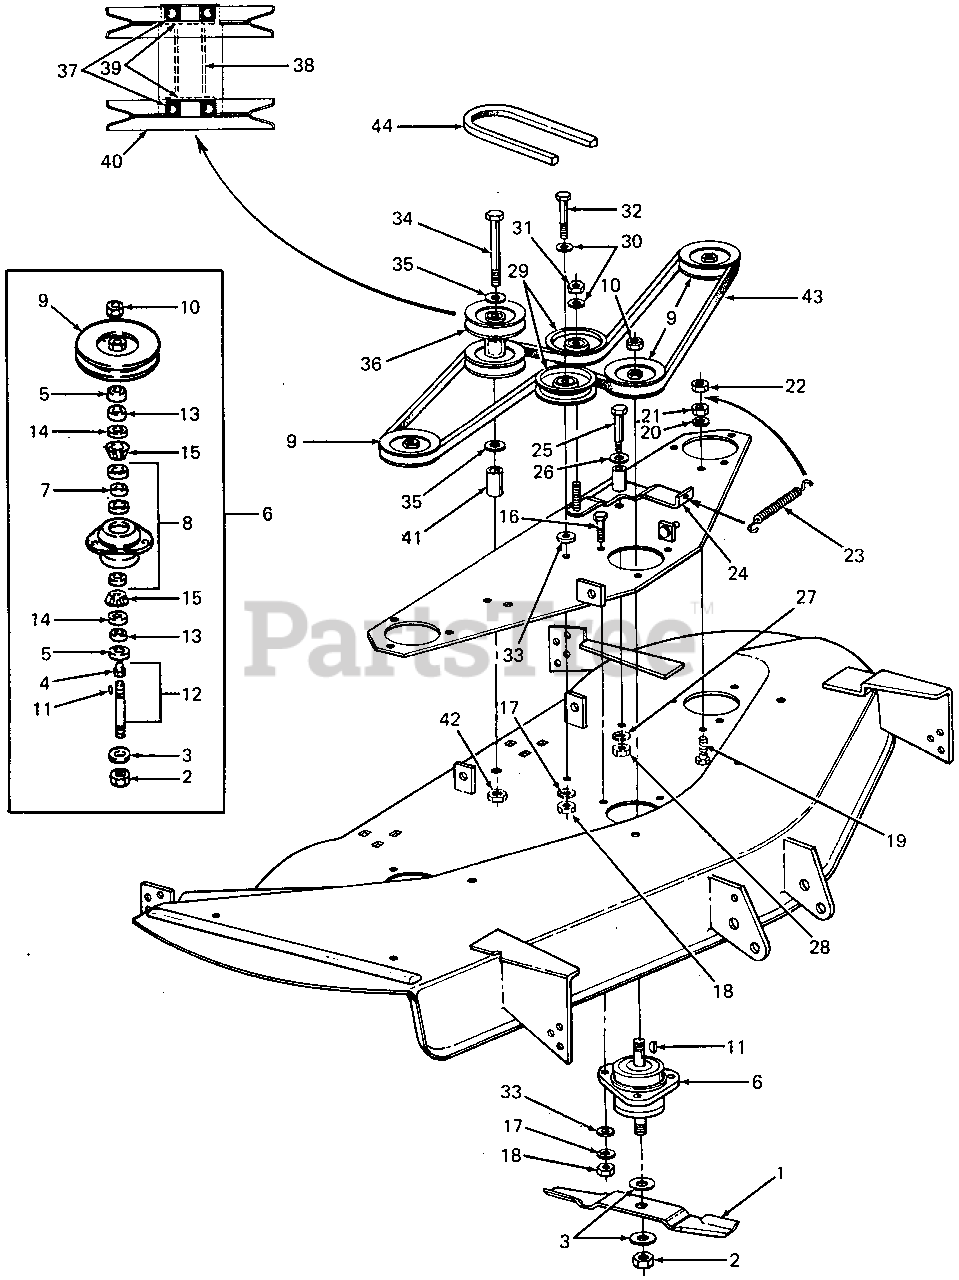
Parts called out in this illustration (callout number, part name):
2	Nut, Hex, 3/4-16 GR8
3	Washer, Flat, .781 X 2.0 X .105 Thk HDN
4	Fitting, Lube, 3/16
5	Cup, Spindle HDN
6	Spindle Service Kit
7	Spacer, Bearing
8	Housing, Spindle w/Cups
9	4L V-Pulley, 4.62 OD X .75 ID
10	Nut, Hex Jam, 3/4-16
11	Key, #91 Woodruff, 1/4 X 3/4 HDN
12	Kit, Shaft w/Seal
13	Spacer, .755 X 1.25 X .44 Lg
14	Seal, Oil, 1.25 X 1.874 X .25
15	Cone, Bearing
16	Screw, Hex Cap, 3/8-16 X 1.0 Lg GR5
17	Washer, Lock, 3/8
18	Nut, Hex, 3/8-16
19	Screw, Hex Cap, 5/16-18 X 1.5 Lg GR5
20	Washer, Lock, 5/16
21	Nut, Hex, 5/16-18
22	Nut, Hex Center Lock, 5/16-18 GR5
23	Spring, Extension, .81 OD X 4.75 Lg
24	Arm, Idler
25	Bolt, Shoulder, .68 Dia X 1.56 Lg X 7/16-14 Trd
26	Washer, Flat, .793 X 1.24 X .060 Thk
27	Washer, Lock, 7/16
28	Nut, Hex, 7/16-14 GR5
29	Pulley, Flat Idler, 3.88 OD X .38 ID
30	Washer, Flat, .406 X .75 X .063 Thk
31	Nut, Hex Center Lock, 3/8-16 GR5
32	Screw, Hex Cap, 3/8-16 X 2.0 Lg GR5
33	Washer, Flat, .385 X 1.0 X .127 Thk
34	Bolt, Hex, 5/8-18 X 5.0 Lg GR5
35	Washer, Flat, .630 X 1.0 X .063 Thk HDN
36	Pulley Assy, Double
37	Bearing, Ball, .62 ID X 1.38 OD X .44 Thk
38	Spacer, Pulley, .64 ID X .81 OD X 2.25 Lg
39	Snap Ring, Internal
40	Pulley, Double
41	Spacer, .64 X 1.25 X 1.00 Lg
42	Nut, Hex Center Lock, 5/8-18
43	V-Belt, 1/2- X 86" Lg - A Full
44	V-Belt, 4L X 59" Lg
